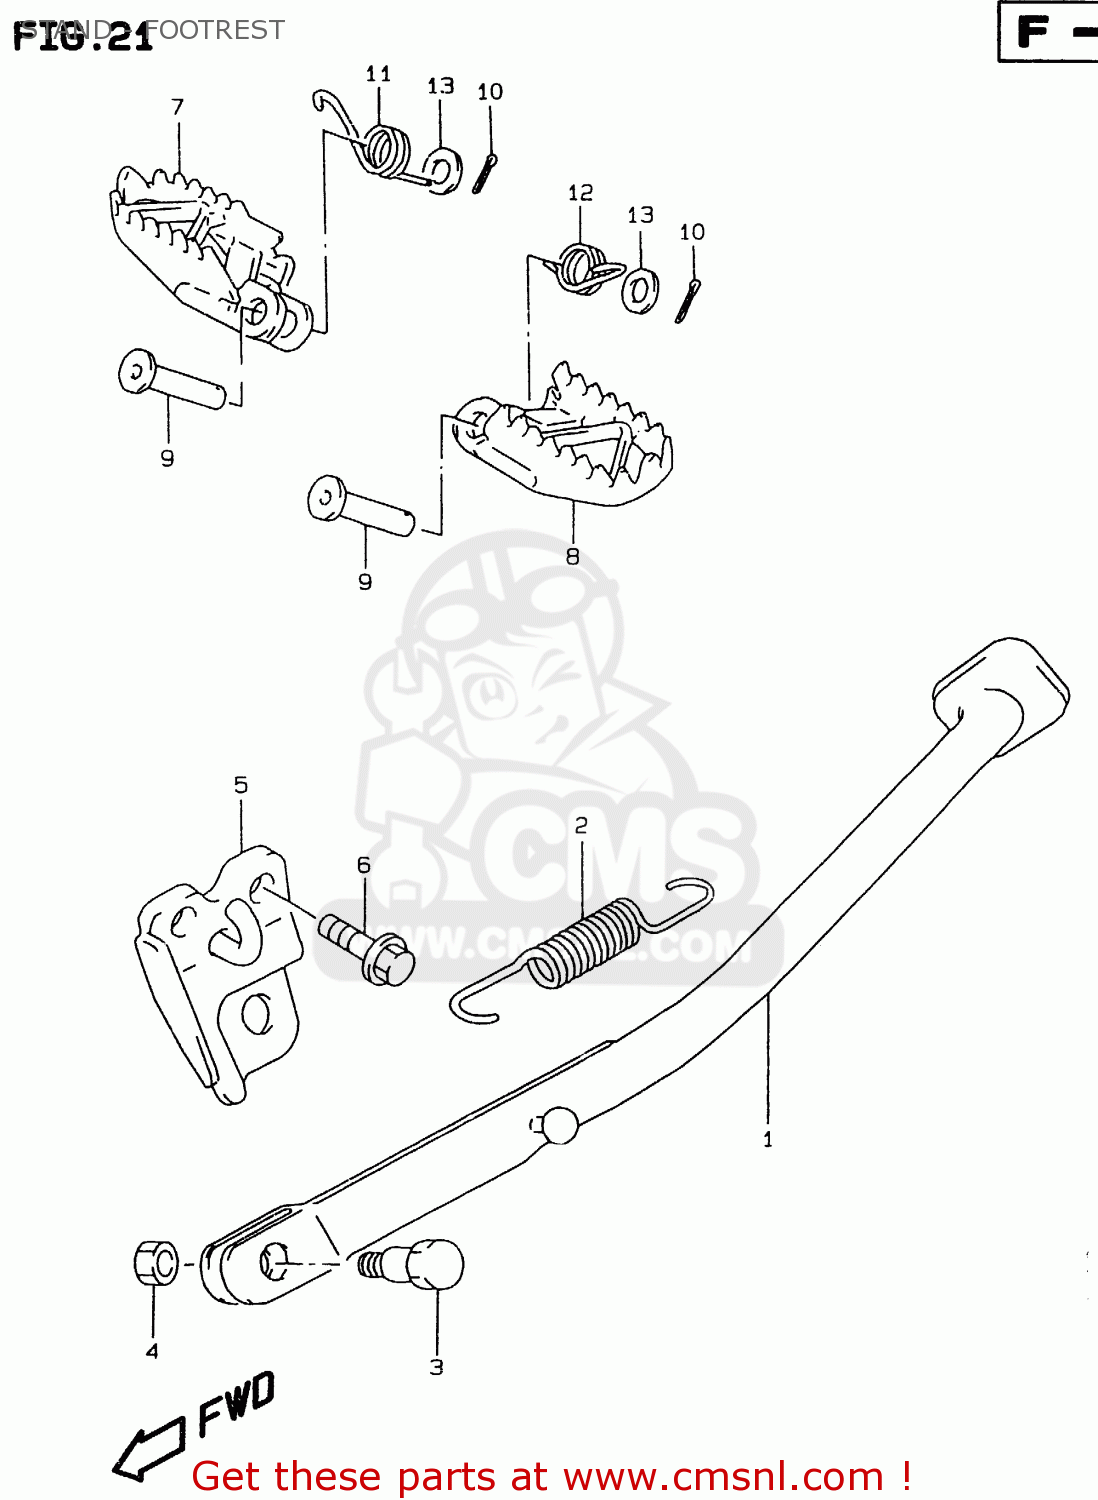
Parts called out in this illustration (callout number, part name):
1	STAND,PROP(SILVER)
2	SPRING
3	BOLT(10X30)
4	NUT
5	BRACKET,PROP STAND
6	BOLT(10X25)
7	FOOTREST,R
8	FOOTREST,L
9	PIN(10X41.5)
10	PIN 25X20
11	SPRING
12	SPRING
13	WASHER
